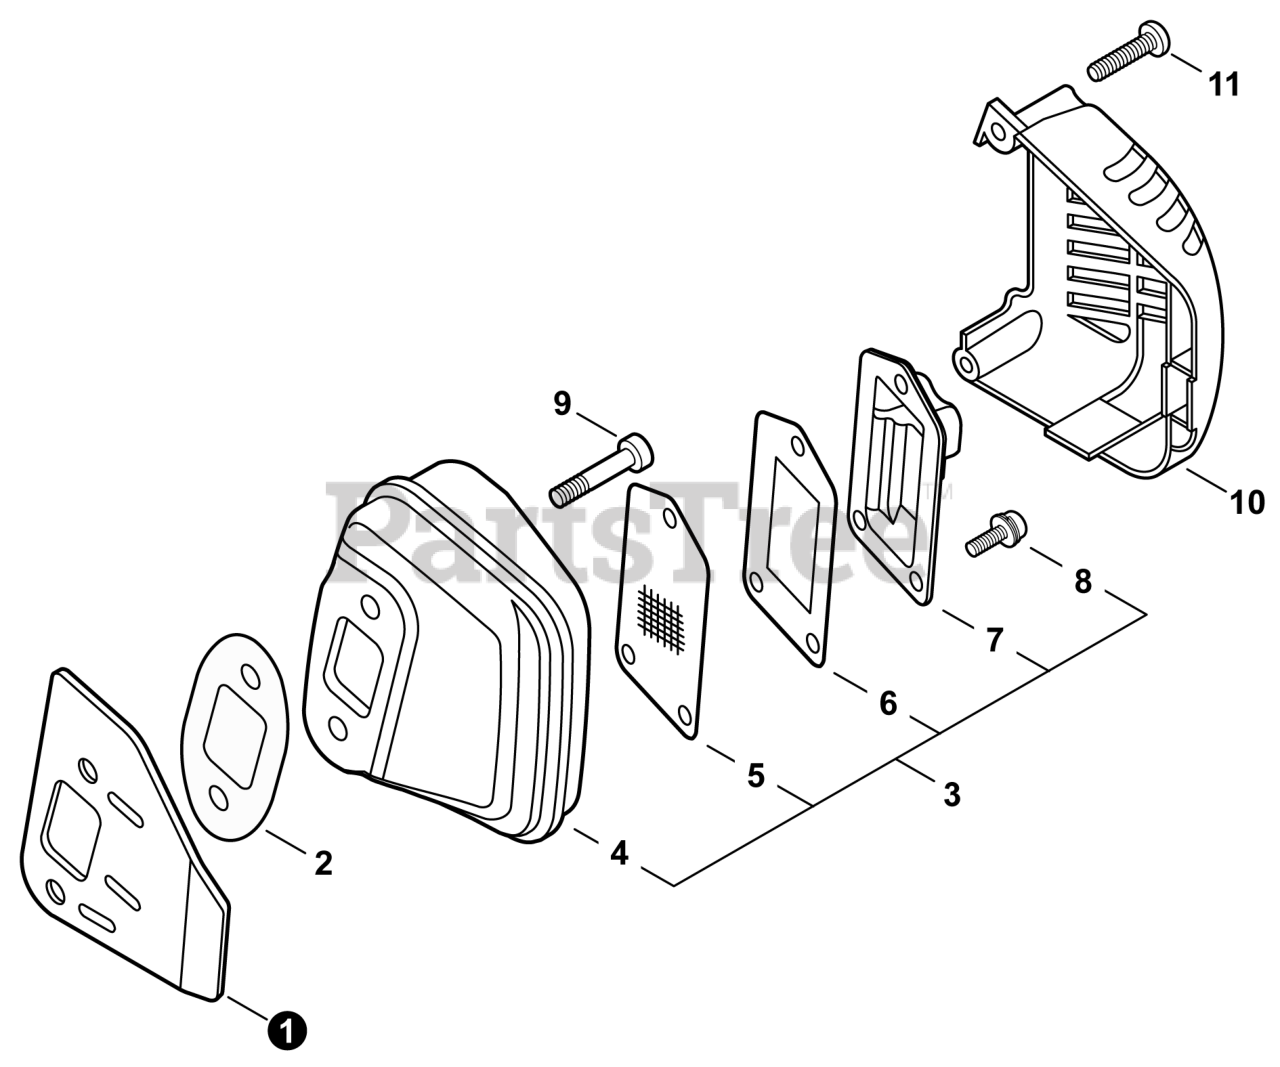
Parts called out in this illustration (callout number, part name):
1	HEAT SHIELD, EXHAUST
2	GASKET, EXHAUST
3	MUFFLER ASSY
4	MUFFLER
5	SCREEN, SPARK ARRESTER
6	GASKET, EXHAUST
7	GUIDE, EXHAUST
8	SCREW 4×10
9	BOLT M5×18
10	COVER, MUFFLER
11	SCREW 4×16
